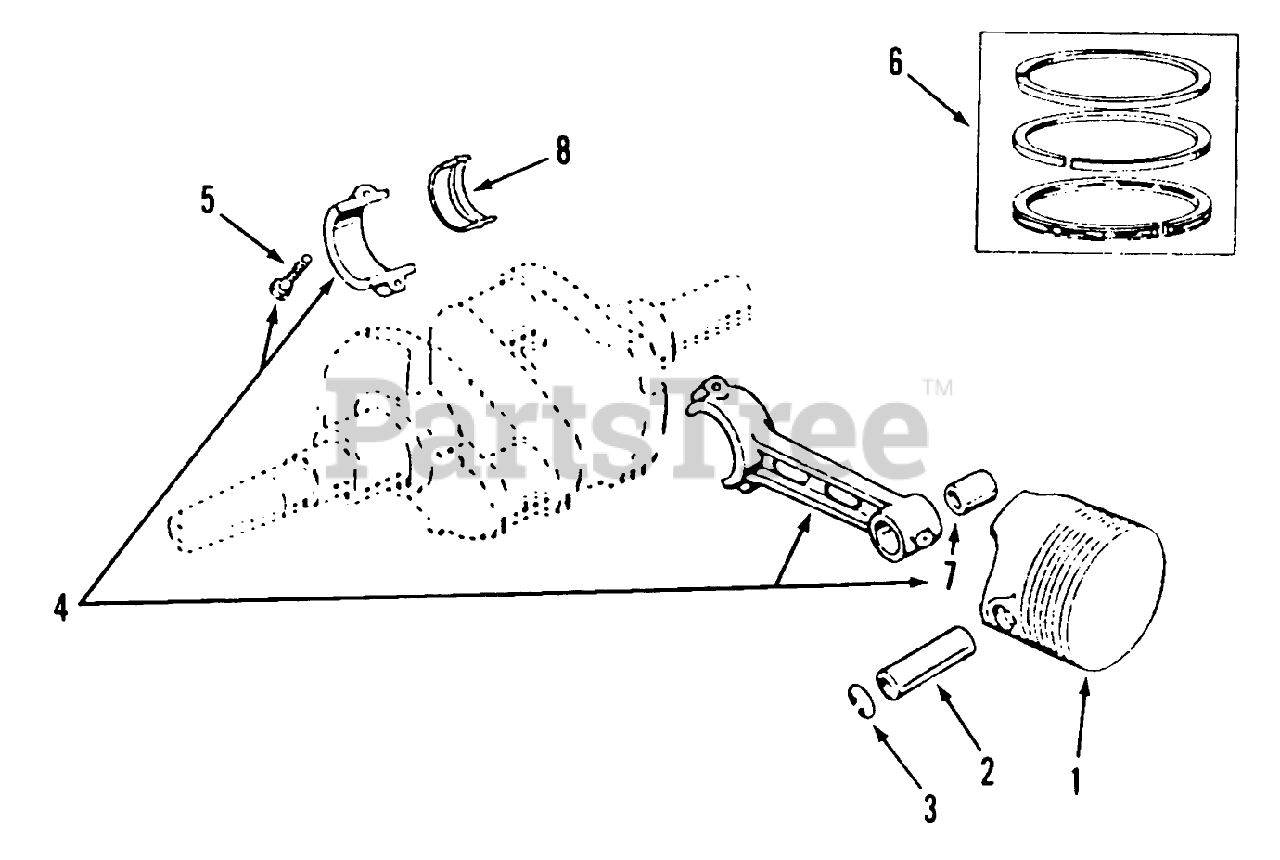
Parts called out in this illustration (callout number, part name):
1	Piston Pin (Incl. Pin Retaining Ring)
2	PIN-PISTON
4	ROD-CONNECTING
5	BOLT-PLACE
6	Set-Piston Ring
7	BUSHING-PISTON PIN
8	Bearing-Connecting Rod, Half
